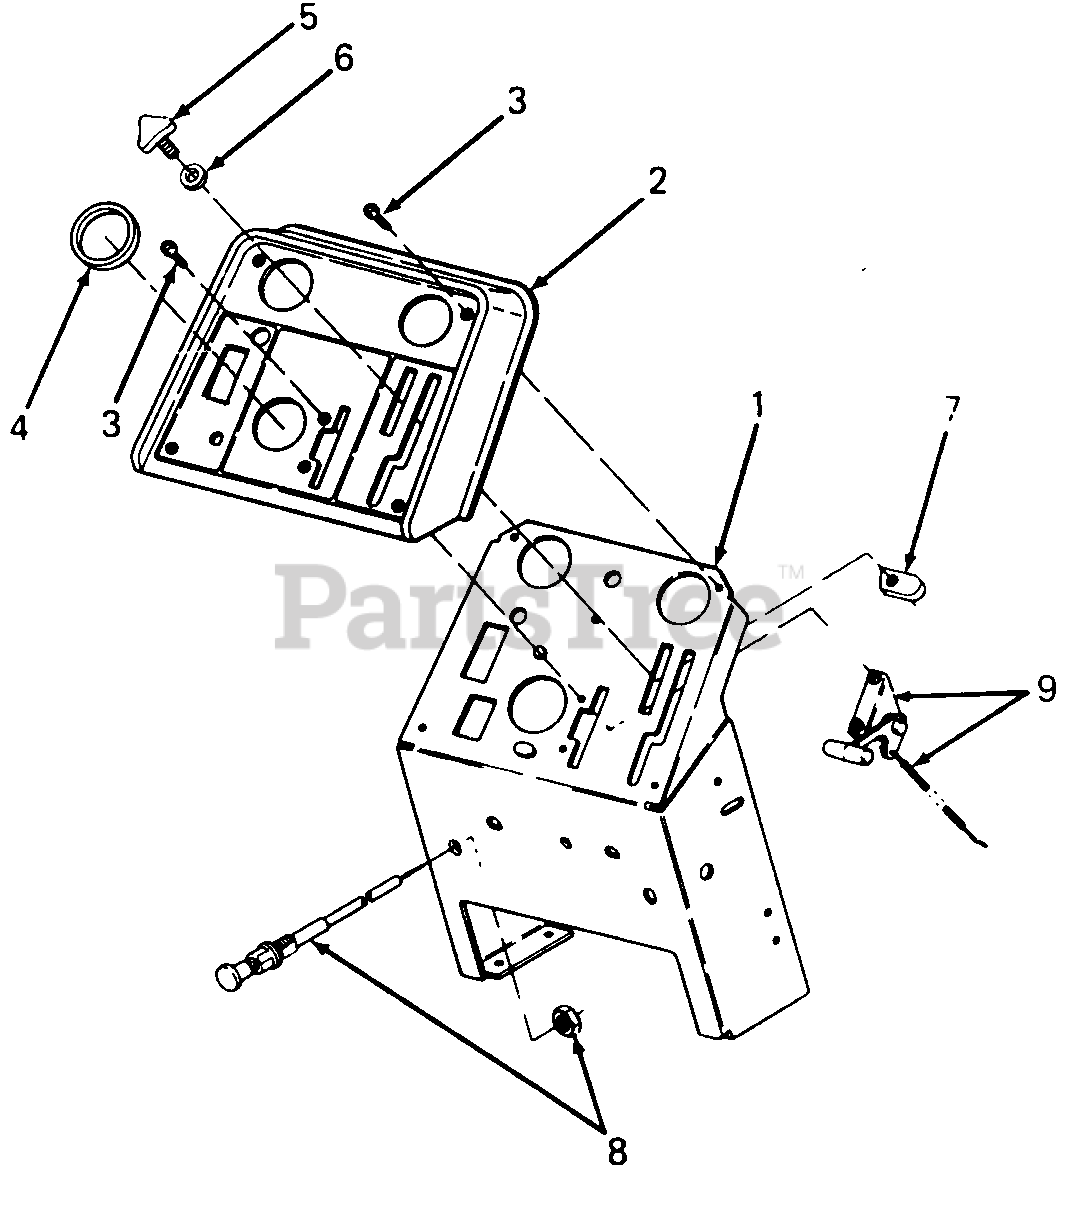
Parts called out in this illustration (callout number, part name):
2	Panel, Instrument
3	Screw, Pan Hd Cutting, #10-24 X .75 Lg
4	Grommet, Instrument Panel
6	Washer, Flat, .266 X .625 X .035 Thk
7	Stop, Detent Handle
8	Choke Cable w/Nut
9	Control, Throttle
